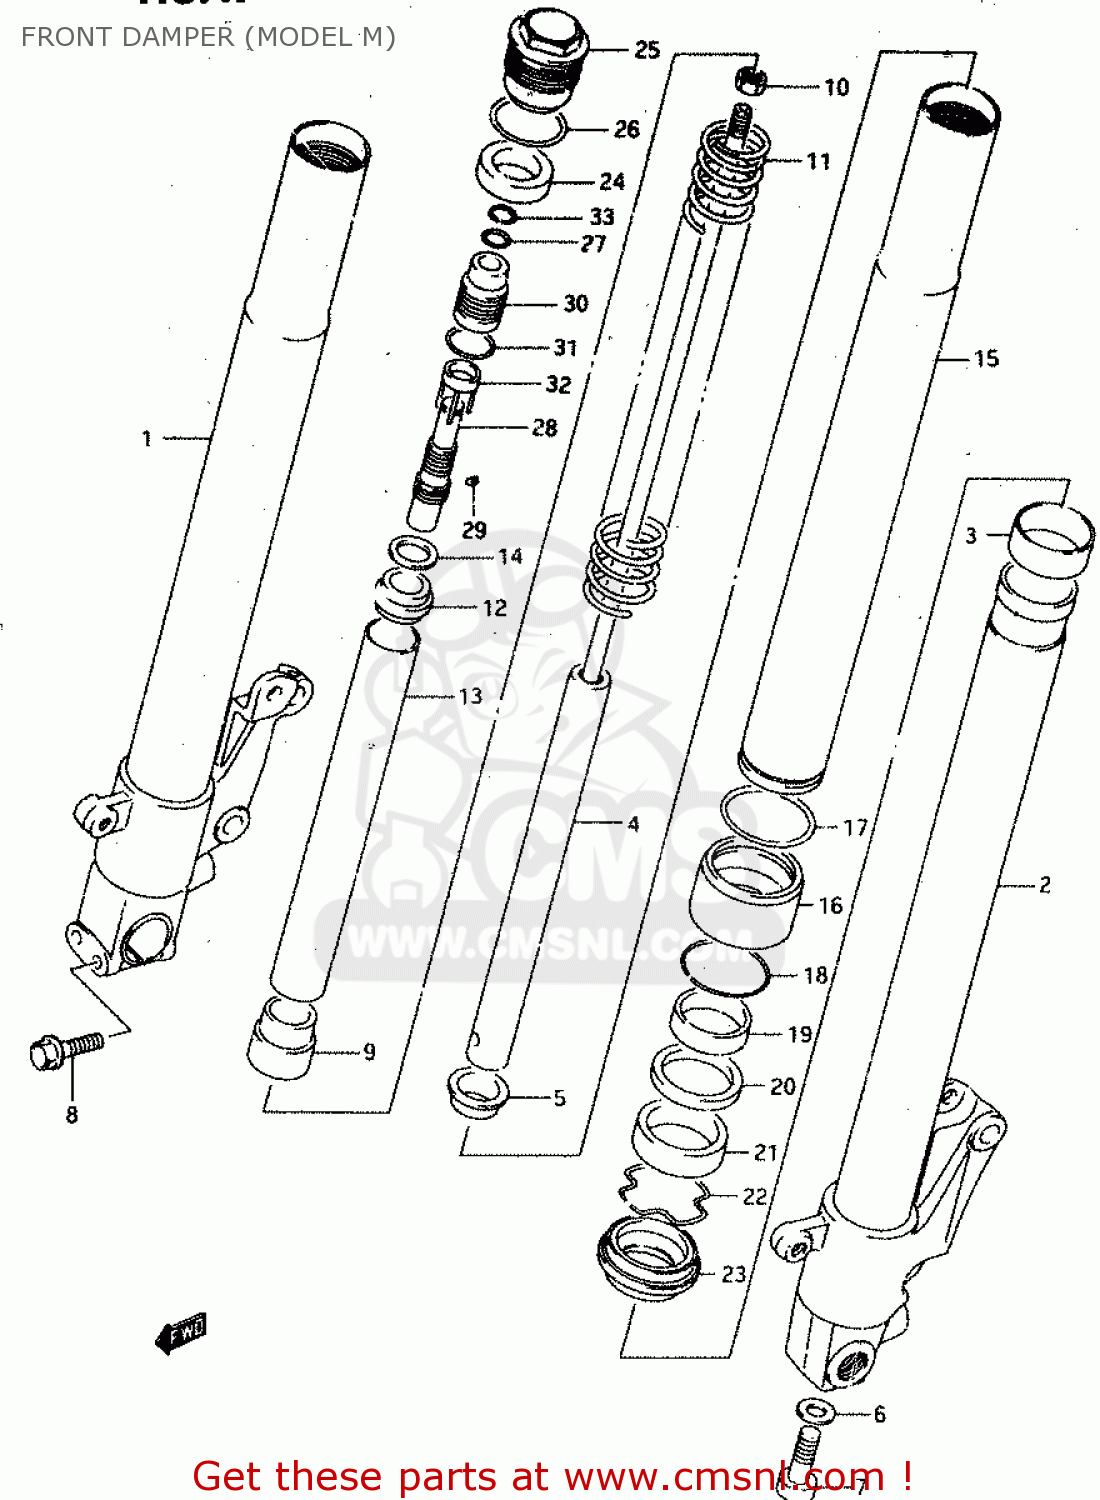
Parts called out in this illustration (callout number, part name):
1	TUBE, INNER
2	TUBE,INNER,L
3	BUSH,SLIDE
4	DAMPER,FR
5	PLATE,CENTERING
6	GASKET (NAS)
7	BOLT,CTR
8	BOLT
9	JOINT,SPRING LWR
10	NUT,ROD
11	SPRING,MAIN
12	GUIDE,SPRING UPR
13	SPACER,SPRING
14	GUIDE,SPRING
15	TUBE, OUTER
16	CASE,OIL SEAL
17	O RING
18	RING,SNAP
19	BUSH,GUIDE
20	SPACER,SEAL
21	SEAL,OIL
22	CIRCLIP,FORK OIL SEAL
23	DUST SEAL,FRONT FORK
24	RUBBER,SEAT
25	BOLT, FORK
26	O RING,FORK BOLT
27	O RING
28	CASE,ADJUSTER
29	SCREW
30	ADJUSTER,SPRING
31	O RING
32	PLATE, SPRING ADJUSTER
33	RING,STOPPER
